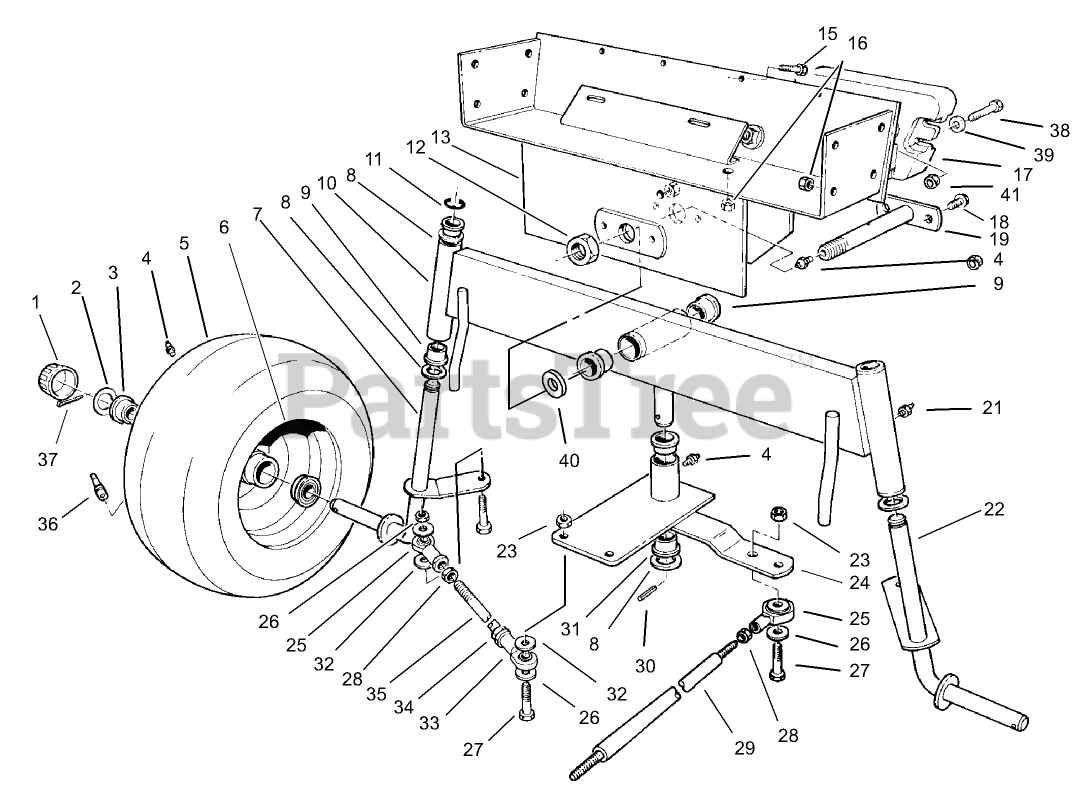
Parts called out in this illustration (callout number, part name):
1	CAP-HUB
2	WASHER-PLAIN
3	Bearing
4	FITTING-GREASE
6	FRONT WHEEL
7	Spindle R.H.
8	WASHER-THRUST
9	BUSHING PM
10	Axle-Rear (Incl. Ref. #9)
11	E-RING
12	NUT-LOCK NI
13	Frame-Rear
15	SCREW-HH
16	NUT-LOCK, NI
17	WEIGHT-REAR
18	SCREW-HHFTF
19	Axle-Pivot
21	GREASE FITTING
22	Spindle LH.
23	NUT-LOCK, NI
24	Plate-Pivot (Incl. Ref. 31)
25	BALL JOINT RH
26	WASHER-FLAT
27	SCREW-HH
28	NUT-JAM
29	Rod-Steering
30	PIN-ROLL
31	BEARING-FLANGE
32	WASHER
33	BALL JOINT LH
35	TIE ROD - STEERING
36	STEM-VALVE
37	PIN-COTTER
38	SCREW-HH
39	WASHER-FLAT
40	WASHER-FLAT
41	NUT-HH
